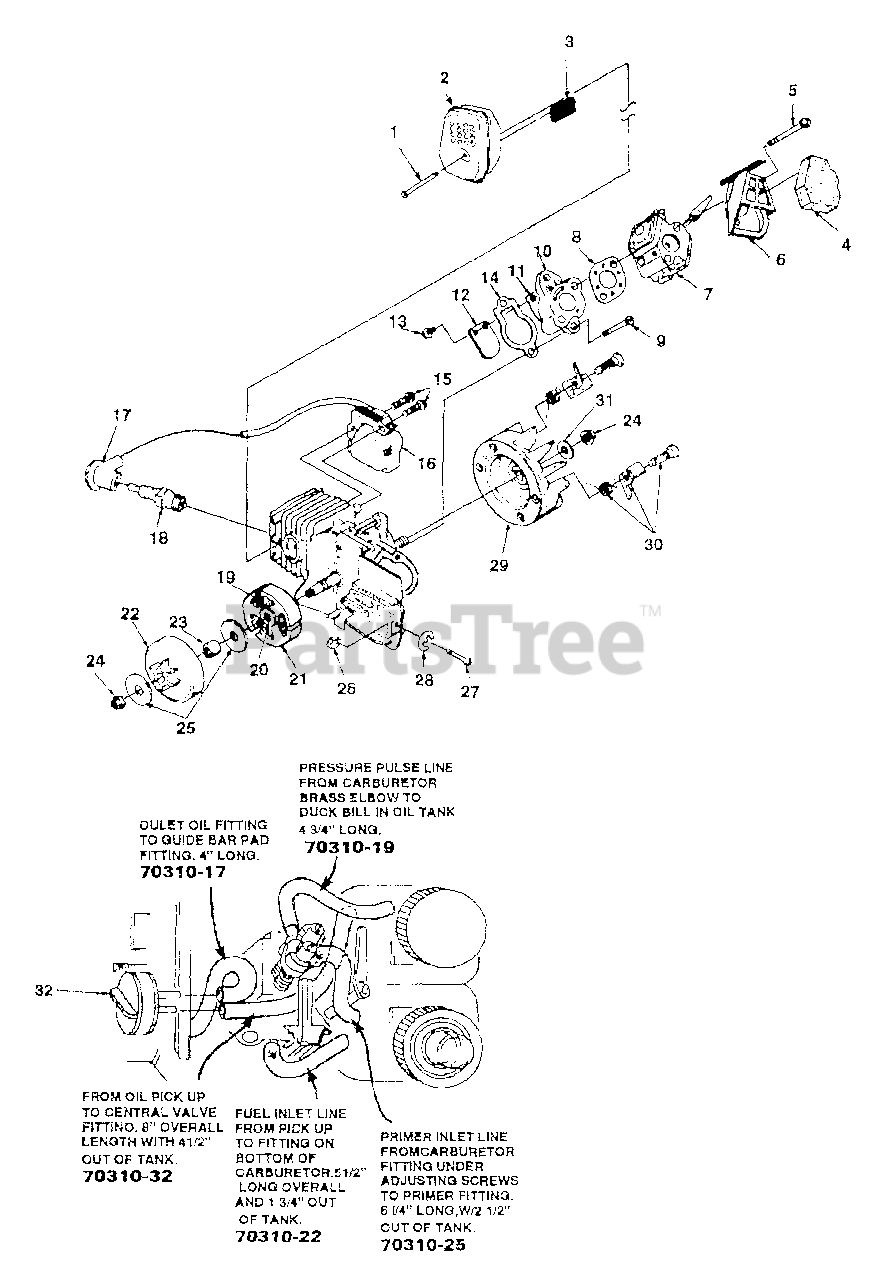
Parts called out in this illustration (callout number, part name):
1	SCREW-Machine Hex Sems (#8 -32 X 3/4")
2	MUFFLER
3	SCREEN-Spark Arrestor
4	FILTER-Air
5	SCREW-Thread Forming
6	BOX-Air Filter
7	CARBURETOR (Zama)
8	GASKET-Carburetor
9	SCREW-Plastite, (10-14 X 1")
10	HEAT DAM
11	REED
12	STOP-Reed
13	SCREW-Hex Taptite (4-40 X 3/8")
14	GASKET-Intake Manifold
15	SCREW-Thread Forming (8-32 X 1")
16	MODULE-Ignition
17	TERMINAL
18	SPARK PLUG (Champion DJ7Y)
19	SPRING-Clutch
20	SPIDER-Clutch
21	SHOE-Clutch
22	SPROCKET & DRUM
23	BEARING
24	NUT-Rotor (5/16-24)
25	WASHER-Thrust
26	PIN-Adjusting
27	SCREW & E-RING KIT
28	E-RING
29	ROTOR & STARTER PAWL
30	STARTER PAWL KIT
31	WASHER-(5/16")
32	OIL VALVE
